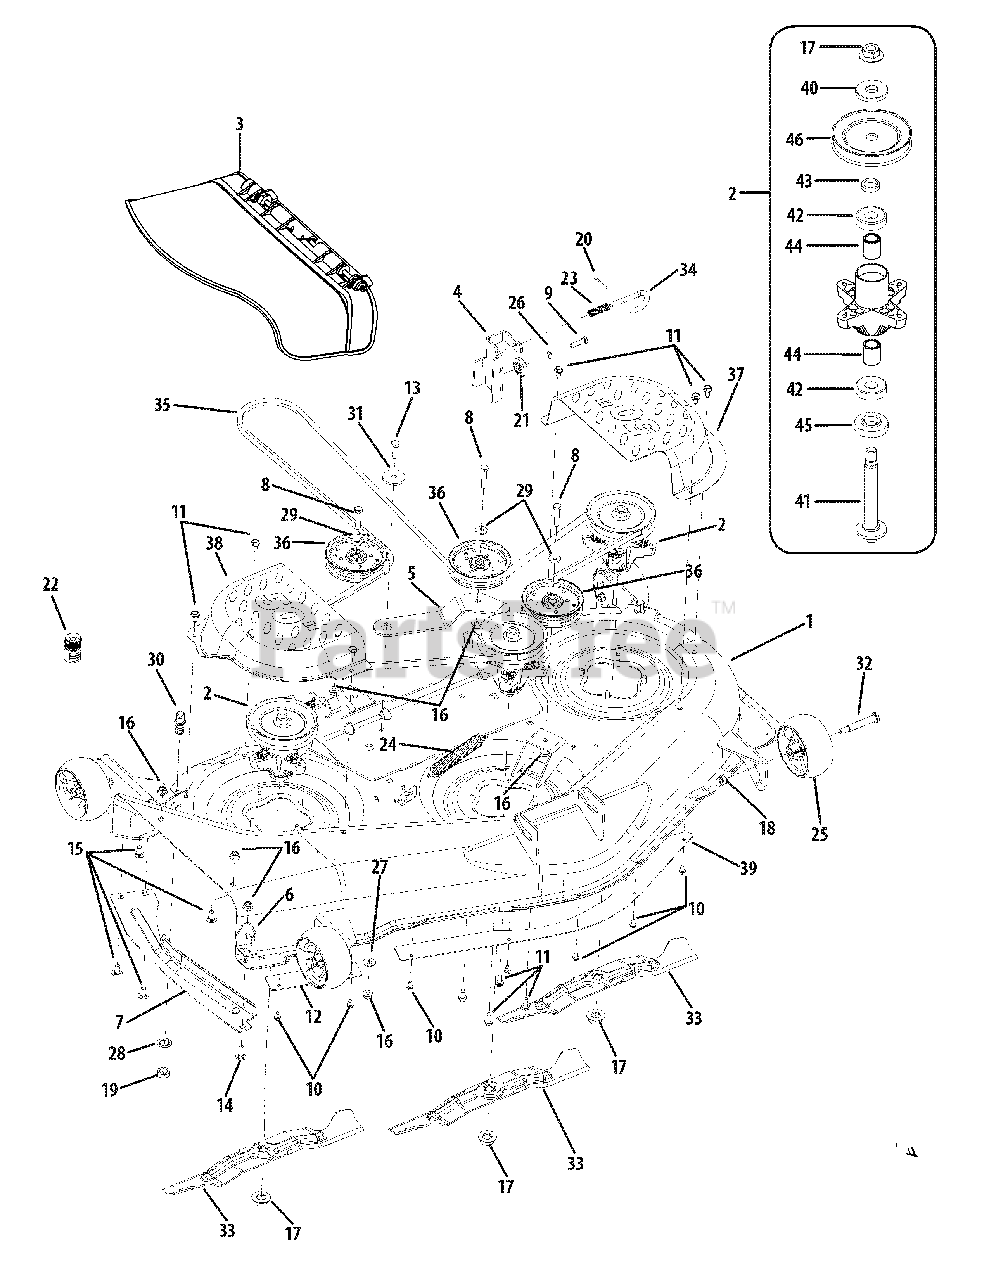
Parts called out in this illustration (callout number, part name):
1	Deck Housing - Black Jack
2	Spindle Assembly
3	Discharge Chute Assembly
4	Deck Hanger Bracket
5	Idler Arm
6	Stop Bracket
7	Finger Guard
8	Hex Cap Screw, 3/8-16 x 1.75
9	Hex Cap Screw, 5/16-18 x 1.25
10	Hex Washer Head Screw, 1/4-20 x
11	Hex Washer Head Screw, 5/16-18 x .750
13	Hex Cap Screw, 3/8-16 x 1.25
14	Hex Screw, 3/8-16 x 1.00
15	Carriage Screw, 3/8-16 x .75
16	Hex Insert Flange Lock Nut, 3/8-16
17	Hex Flange Nut, 5/8-18
18	Hex Flange Lock Nut, 3/8-16
19	Hex Nut, M16-1.5
20	Cotter Pin, 1/8 x 1.25
21	Deck Adjustment Gear
22	Water Nozzle Adapter
23	Compression Spring, .535 x 1.751
24	Extension Spring, .94 x 6.74
25	Deck Ball Wheel, 5.0
26	Lock Washer, 5/16
27	Bell Washer, .45 x 1.0 x .062
28	Internal Tooth Lock Washer, 5/8
29	Flat Washer, .38 x .93 x .110
30	Deck Wash Nozzle
31	Shoulder Spacer, .884 x .190
32	Shoulder Screw, .5 x 2.5 x 3/8-16
33	Blade, 2 in 1, 17.9
34	Deck Hanger Rod
35	V-Belt Type A Sec x 134
36	Idler Pulley, 4.25 Dia
37	Belt Cover, LH
38	Belt Cover, RH
39	Center Skirt
40	Flat Washer, .76 x 1.50 x .12
41	Spindle Shaft, 5.75
42	Ball Bearing
43	Spacer, .79 x 1.25 x .175
44	Spacer, .80 x 1.10 x 1.32
45	Spacer, .79 x 1.82 x .55
46	V-Type Pulley, 5.39
